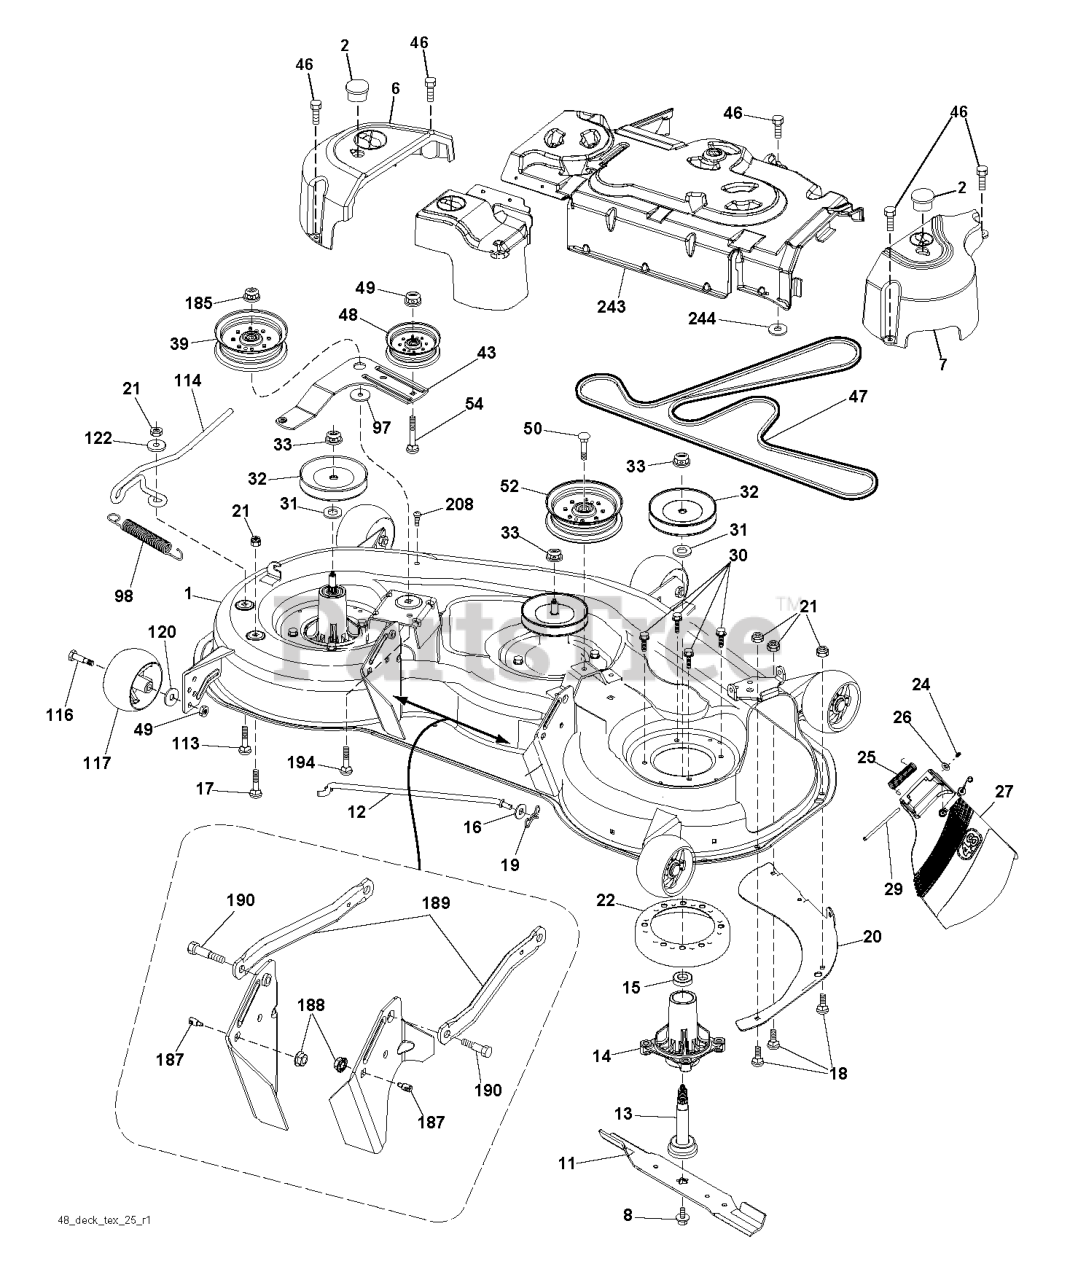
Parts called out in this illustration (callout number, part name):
1	DECK WELDMENT
8	BOLT.WASHER.ASM.7/16-2
11	48" HI-LIFT BLADE
12	ROD.ANTI.SWAY.48/54"K4
13	SHAFT ASM MANDREL
14	RP.HOUSING.MANDREL.4PT.
16	WASHER
17	BOLT.CARR.5/16-18X5/8.SHORT
18	BOLT
19	PIN.COTTER.5/16.BOW TI
20	BAFFLE, VORTEX MWR
21	LOCKNUT
22	STRIPPER.MANDREL.ROUND.BLACK
24	CAP-SLEEVE LT
25	SPRING, TORSION
26	NUT PUSH M
29	ROD.HINGE
30	SCREW, WASHER HEAD
31	WASHER.SPACER.MANDREL
32	PULLEY MANDREL
33	NUT.FLANGE.LOCK.TOP
39	RB PULLEY.IDLER.4.50/HUB SPEC
43	ARM.IDLER
46	SCREW.1/4-20X5/8
47	BELT.DRIVE.DECK
48	PULLEY.IDLER.48"PRIMARY
49	NUT LOCK FLG 3/8-16 UNC
50	SCREW TT 3/8-16X2-1/4 UNC
52	PULLEY.IDLER.2006
54	BOLT.3/8-16X1.50
98	SPRING, DECK DRIVE
113	BOLT CRT
114	ROD.TENSION.RELIEF.TEX (2 2)
116	BOLT.SHOULDER.3/8-16X3-5/8.
117	RP WHEEL. GUAGE RALLY
120	WASHER
122	BUSHING.RELIEF.TENSION
185	NUT.LOCK.FLANGE.7/16
187	STUD.FASTNER.W/ANTI-ROTATE
188	NUT LOCK HEX FLANGE 5/16-18
189	ARM.SUSPENSION.MOWER
190	BOLT.SHOULDER
194	BOLT.CARR.SQNK.7/16
208	SCREW 3/8-16X1/2
244	PALNUT 1/4
